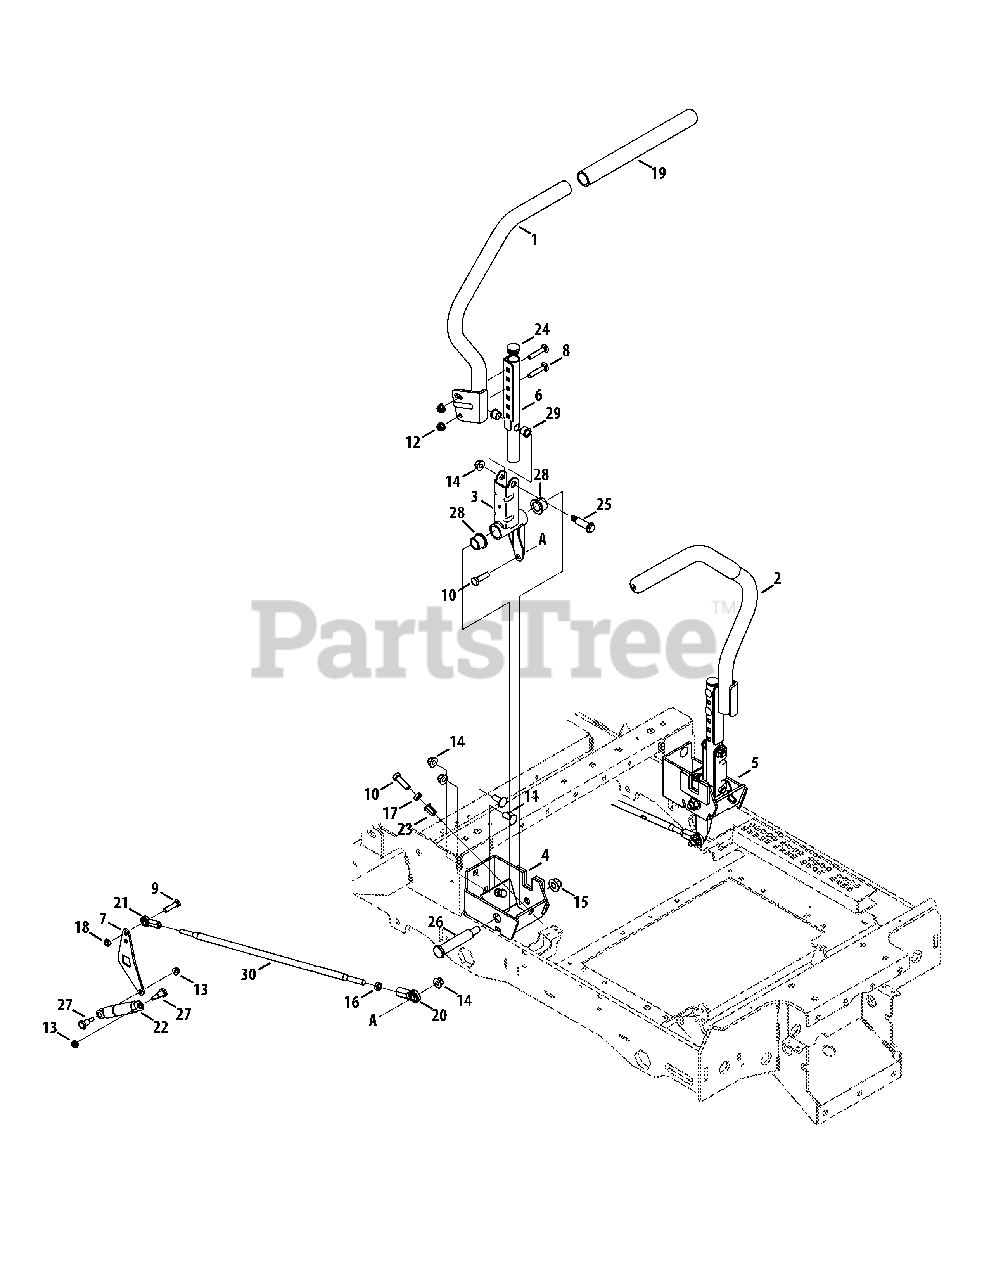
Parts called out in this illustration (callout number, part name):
1	Lapbar Lever Assembly, RH
2	Lapbar Lever Assembly, LH
3	Pivot Hub Assembly
4	Pivot Housing, RH
5	Pivot Housing, LH
6	Lapbar Adjustment Tube Assembly
7	Damper Mounting Bracket
8	Carriage Bolt, 5/16-18 x 1.75
9	Hex Cap Screw, 5/16-18 x 1.25
10	Hex Cap Screw, 3/8-16 x 1.25
11	Carriage Bolt, 3/8-16 x 1.00
12	Nut, 5/16-18, Flangelock
13	Nut, 1/4-20, Flangelock
14	Nut, 3/8-16, Flnagelock
15	Nut, 1/2-13, Flangelock
16	Jam Nut, 3/8-24
17	Jam Nut, 3/8-16
18	Nut, Hex Jam, 5/16-18
19	Grip, 1.0 ID
20	Ball Joint, 3/8-24
21	Rod End, 5/16 ID, Female LH
22	Damper Cylinder, .87 OD x 7.06 LG
23	Rivet Nut, 3/8-16
25	Shoulder Screw, .498 Dia. x 1.296
26	Shoulder Bolt, .75 x 3.25, 1/2-13
27	Shoulder Screw, .395 Dia. x .56 LG
28	Bearing, .75 x 1.00 x .73
29	Flange Bushing, .500 ID x .627 OD
